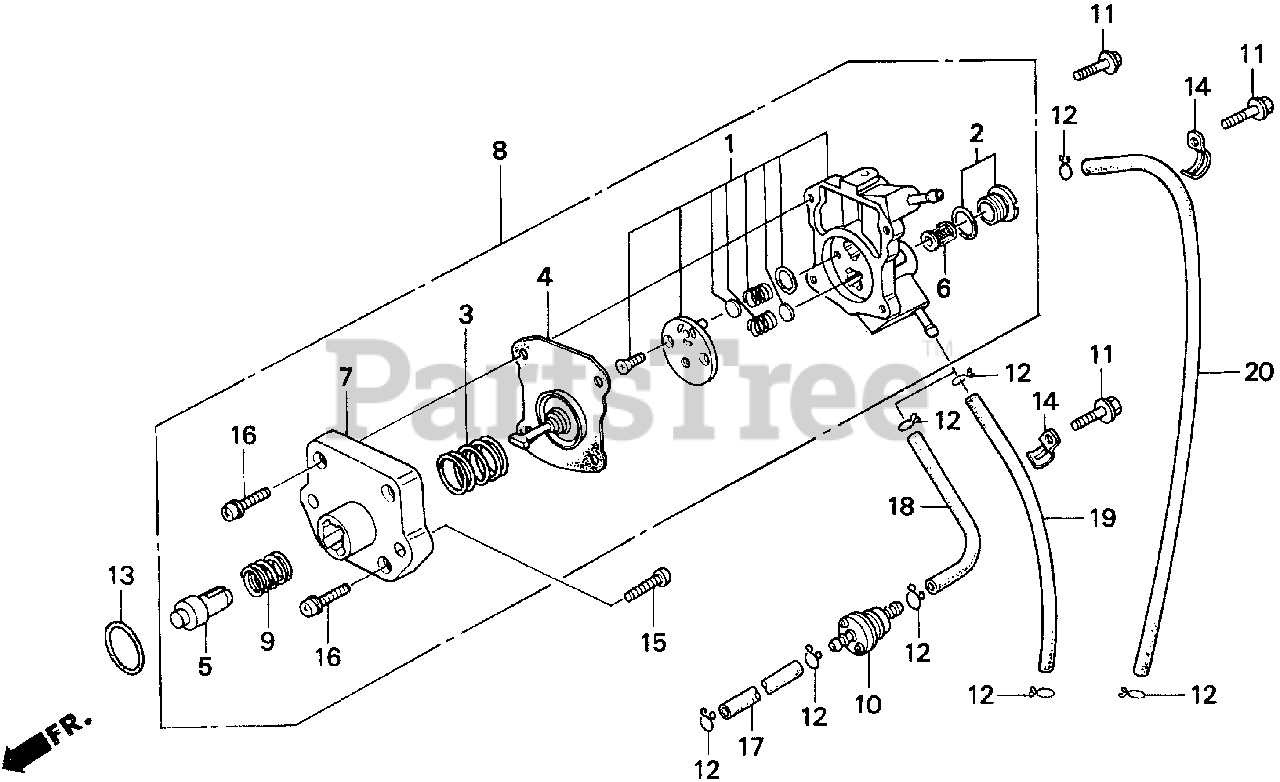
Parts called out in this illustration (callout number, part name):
1	BODY SET, PUMP
2	BOLT SET, HOLDING
3	SPRING, DIAPHRAGM
6	SCREEN, FUEL STRAINER
7	BODY (LOWER)
8	PUMP ASSY., FUEL
9	SPRING, PUSH ROD
10	FILTER, FUEL
11	BOLT, FLANGE (6X28)
12	CLIP, TUBE (B8)
13	O-RING (20.8X2.4)
14	CLIP, WIRE
15	SCREW, PAN (6X20)
16	SCREW-WASHER (4X16)
17	BULK HOSE, FUEL (4.5X3000) (4.5X80)
18	BULK HOSE, FUEL (4.5X3000) (4.5X220)
20	BULK HOSE, FUEL (4.5X3000) (4.5X400)
